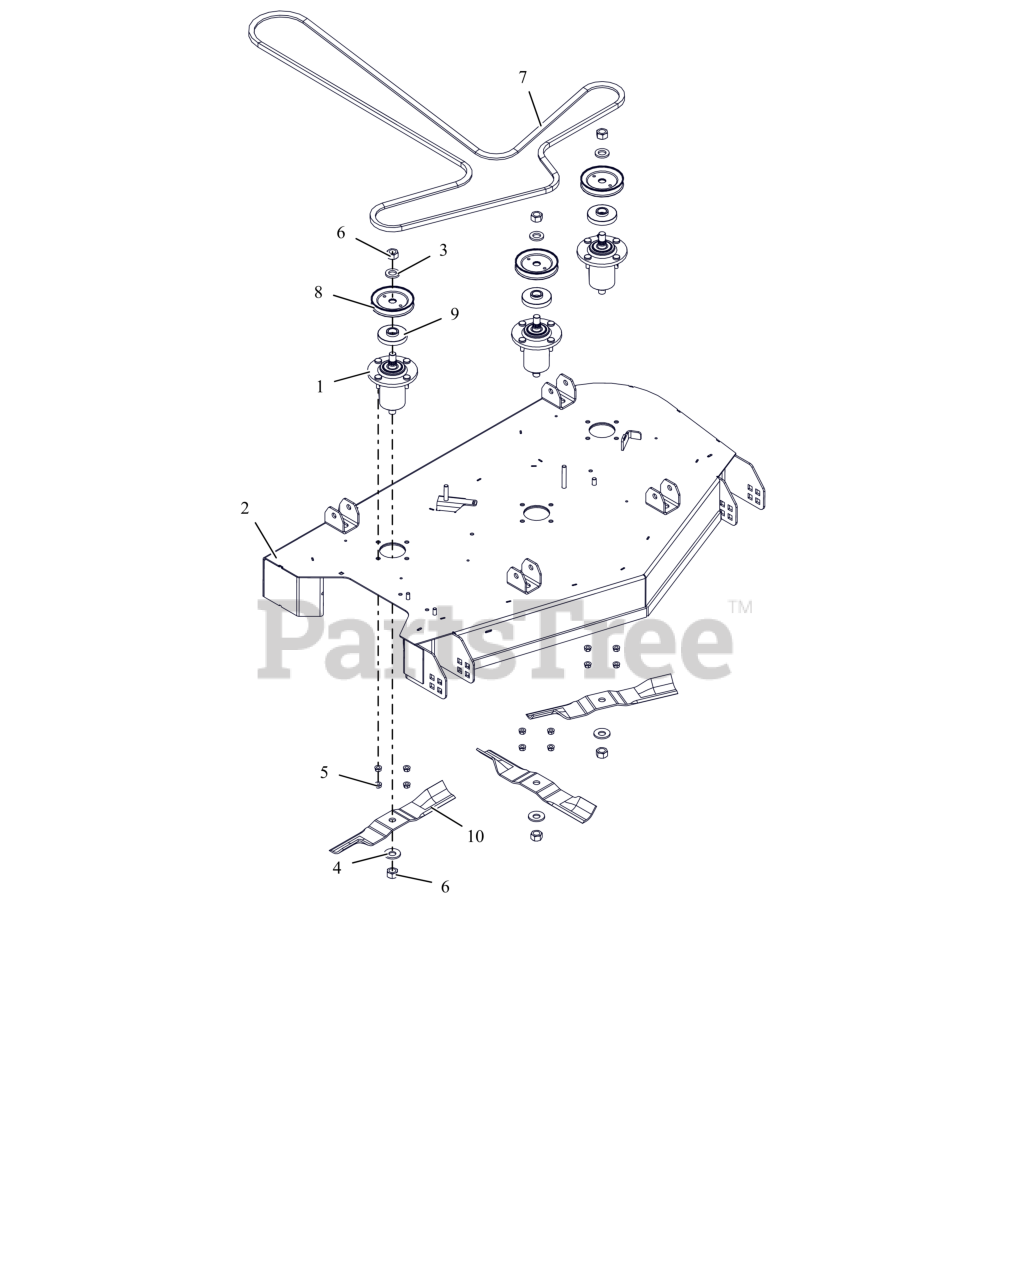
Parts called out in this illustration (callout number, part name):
1	ASM, ALUMINUM SPINDLE SUB
2	KIT,ARIENS DECK 42" WITH DECALS
4	WSHR-BLVL .669X1.535X.138
5	NUT,LK-CTR-FLG .31-18 GF ZCC
6	NUT-STD .625-18 ZCC
7	V-BELT, HA-WRAPPED
8	PULLEY, V-4.00 ODX.625 SPLINE ID
9	SHIELD, DUST
10	BLADE, MOWER 14.5"
